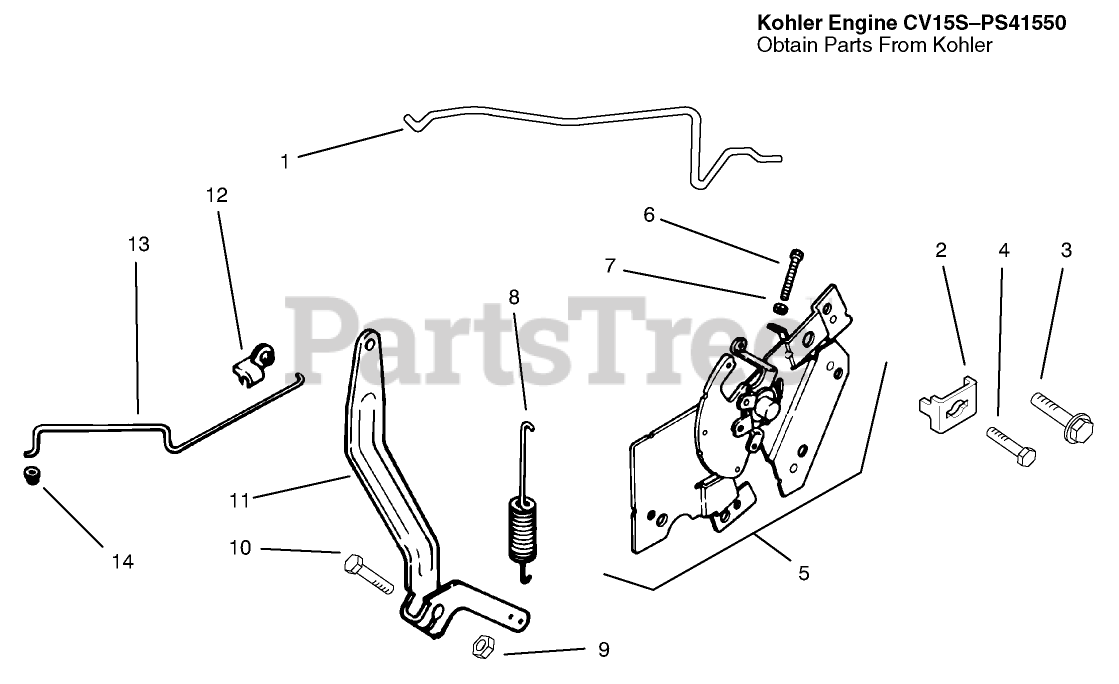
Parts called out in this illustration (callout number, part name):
1	Linkage-Choke (Only On: 72042,72043,72062,72063)
3	Screw Socket
4	Screw M5x0.8x16 (Only On: 72042, 72063, 72062, 72043)
5	Control-ASM INC 6-7 (Only On: 72042, 72063, 72062, 72043)
6	Screw-HHF M4x0.7x28 (Only On: 72042, 72063, 72062, 72043)
7	Nut
8	Spring-Governor (Only On: 72042, 72063, 72062, 72043)
11	Lever-Governor (Only On: 72042, 72063, 72062, 72043)
12	Bushing-Linkage
13	Linkage-Throttle (Only On: 72042, 72063, 72062, 72043)
14	Bushing
